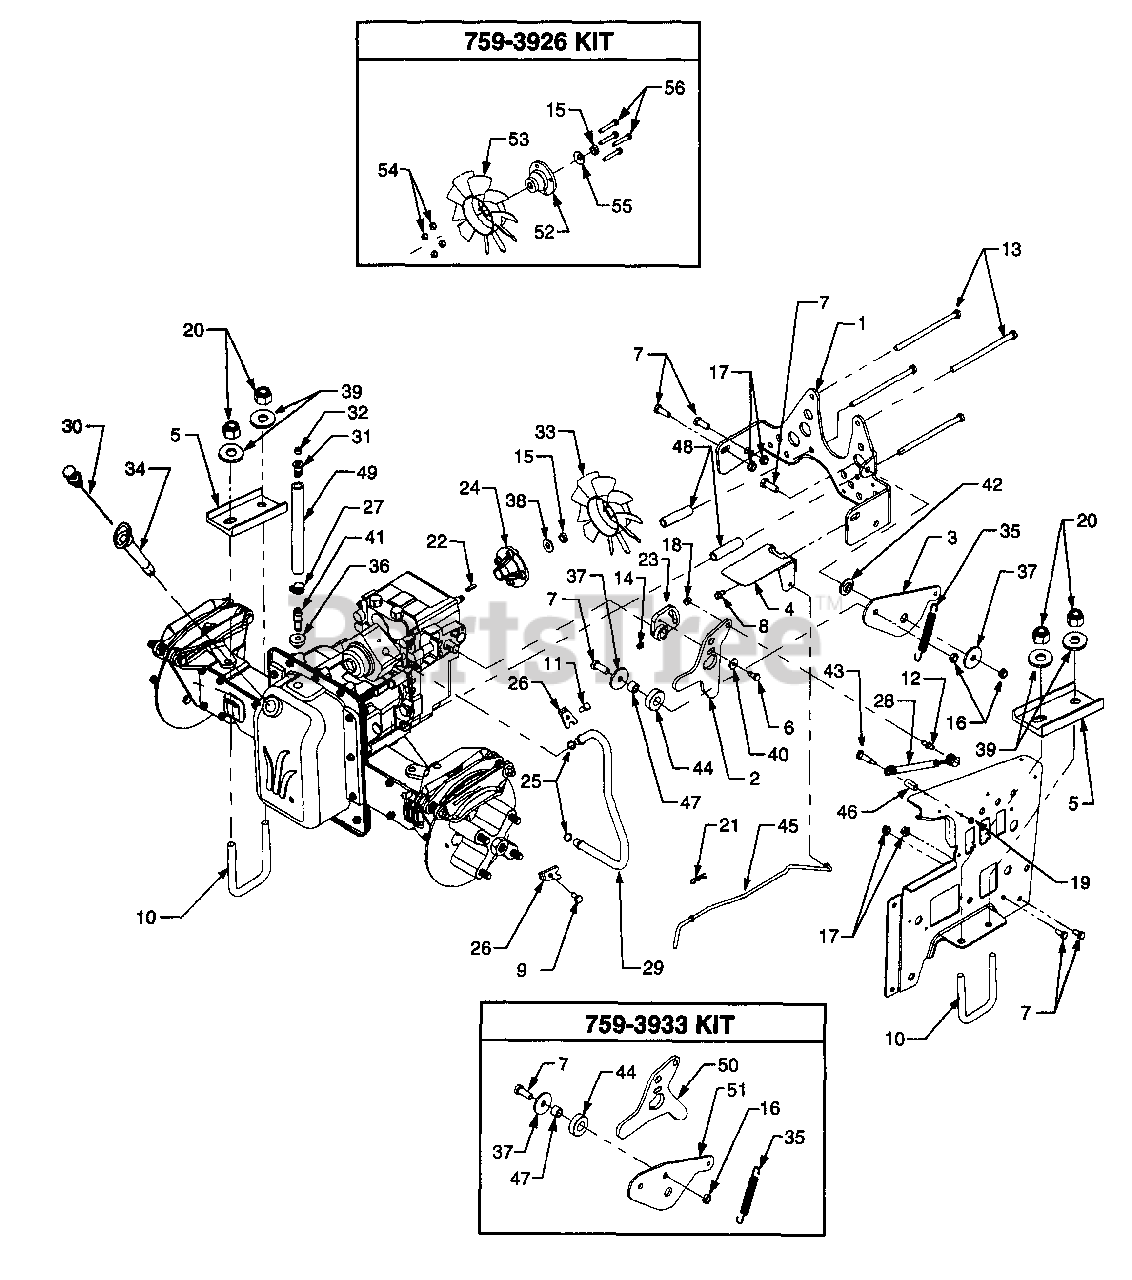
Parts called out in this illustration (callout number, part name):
1	Bracket, Torque
2	Plate, Hydro Neutral Return
3	Link, Neutral Return Bearing
4	Spring Plate, Hydro Bypass
5	Plate, Reinforcement
6	Screw, Hex Cap, 1/4-20 x .625 GR5 Lock
7	Screw, Hex Cap, 3/8-16 x 1.0 GR5
8	Screw, Hex Wash. Hd. Tapp, 1/4-20 x .5
9	Screw, Hex Wash. Hd. Tapp, 1/4-20 x .75
10	Bolt, U-Style
11	Screw, Hex Cap, 1/4-20 x .75 GR5
12	Ball Screw, 5/16-18 x .56
13	Screw, Hex Cap, 5/16-18 x 5.5 GR5 Lock
14	Screw, Set, 5/16 x .5
15	Nut, Hex Ctr. Lock Jam, 3/8-24
16	Nut, Hex Ctr. Lock Jam, 3/8-16
17	Nut, Hex Flange Lock, 3/8-16
18	Nut, Hex Flange Lock, 5/16-18
19	Nut, Hex, 1/4-20
20	Nut, Hex Insert Lock, 1/2-20
21	Pin, Internal Cotter
22	Key, 3/16 x 1/8 x .75
23	Arm, Hydro
24	Adapter, Pump
25	O-Ring, .426 ID x .566 OD x .070
26	Clamp, Tube
27	Clamp, Hose
28	Cylinder, Damper
29	Tube, Hydro Pickup
30	Dipstick, Transmission
31	Plastic Vent
33	Fan, Pump
34	Holder, Dipstick
35	Spring, Extension
37	Washer, Flat, .390 x 1.5 x .1
38	Washer, Flat, .385 x .87 x .092
39	Washer, Flat, .531 x 1.062 x .134
40	Washer, Flat, .26 x .72 x .06
41	Fitting, Tube
42	Spacer, Shoulder
43	Shoulder Bolt
44	Bearing, Ball
45	Rod, Pump Bypass
46	Spacer, .375 x .5 x 1.02
47	Spacer, .375 x .624 x .445
48	Spacer, Hydro, .3223 x .60 x 2.44
50	Plate, Hydro Neutral Return
51	Link, Neutral Return Bearing
52	Adaptor, Pump
53	Fan, Pump
54	Nut, Fan, 1/4-20
55	Washer, Bell, .401 x .87 x .063
56	Screw, Hex Cap Lock 1/4-20 x 1.62
